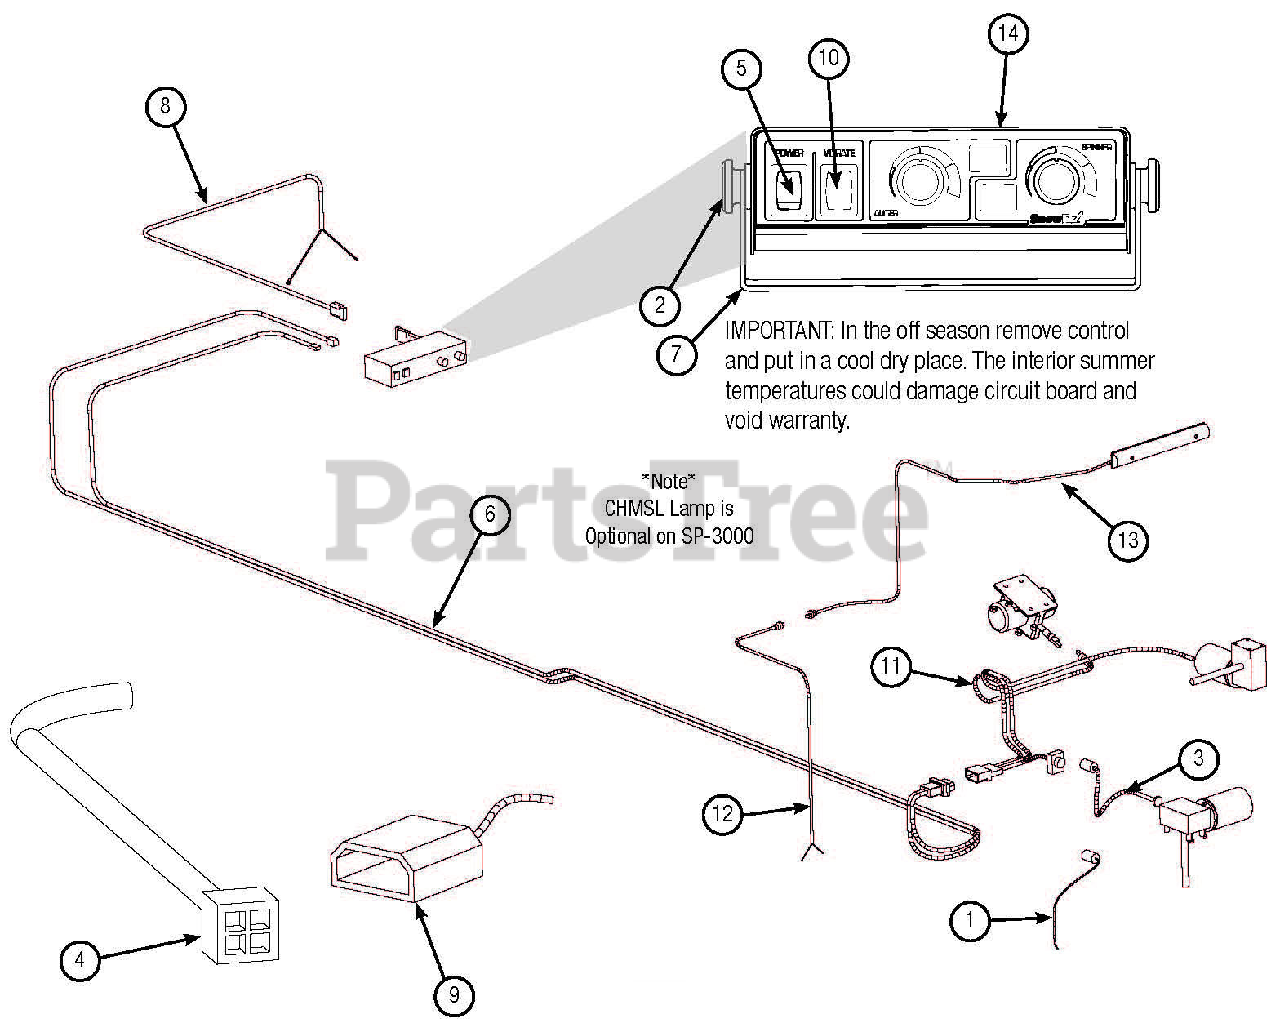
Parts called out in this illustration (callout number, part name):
1	Dust Cover, Standard
2	Bracket Knob
3	Power Cable, 26-1/2"
4	Connector Adapter, 6" Anderson
5	Power Switch , 5 Terminal
6	Vehicle Harness , 311"
7	Controller Mounting Bracket , Pro
8	Control Power Cable , 156" Pro
9	Dust Cover , Pro
10	Vibrator Switch , 3 Terminal Red
11	Spreader Harness , 42"
12	Vehicle Harness , CHMSL
13	CHMSL Brake Light
14	Spreader Control , Pro
